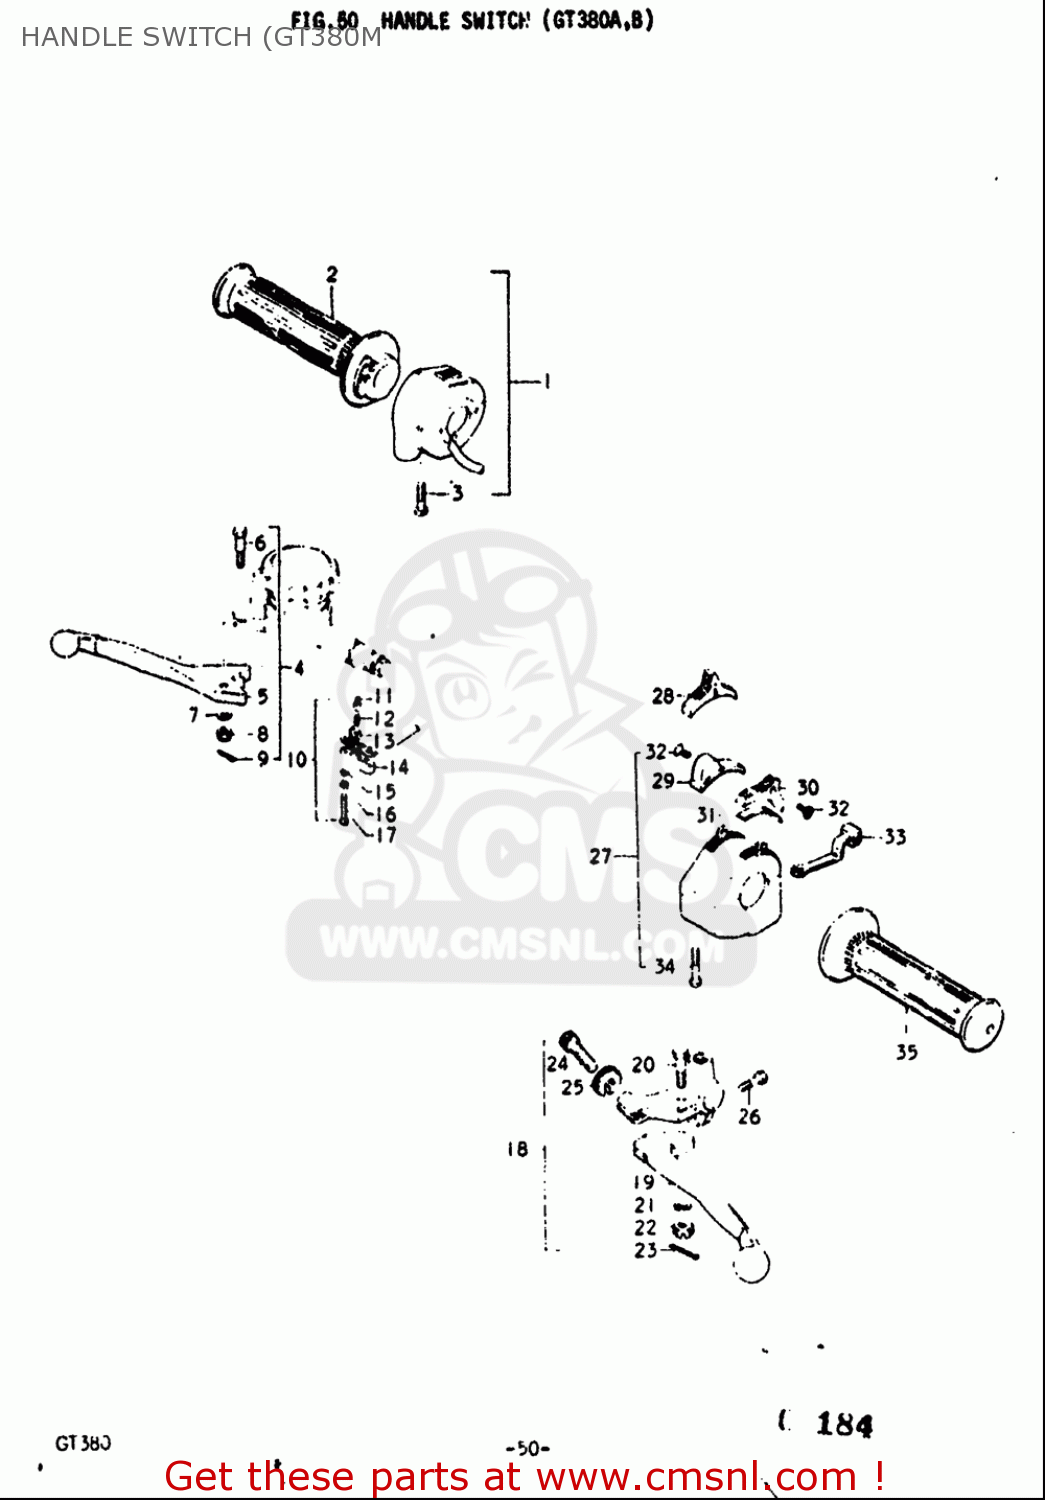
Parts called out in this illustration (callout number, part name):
2	GRIP,THROTTLE
3	SCREW
5	LEVER,BRAKE
6	BOLT
7	WASHER,LOCK
8	NUT,LEVER FITTNG
9	PIN 16X20
10	SWITCH ASSY,STOP
11	CONTACT,SWITCH
12	CONTACT,SWITCH
13	CONTACT,SWITCH
14	COVER,FR BK TERMINAL BASE
15	WASHER
16	WASHER,LOCK
17	SCREW
18	LEVER ASSY,CLUTCH
19	LEVER,CLUTCH
20	BOLT,LEVER PIVOT
21	WASHER,LOCK
22	NUT,LEVER FITTNG
23	PIN 16X20
24	ADJUSTER,CABLE
25	NUT,CABLE ADJUSTER
26	BOLT
28	KNOB,HANDLE SWITCH
30	KNOB
31	PLATE,SWITCH KNOB
32	SCREW
34	SCREW
35	GRIP,L
